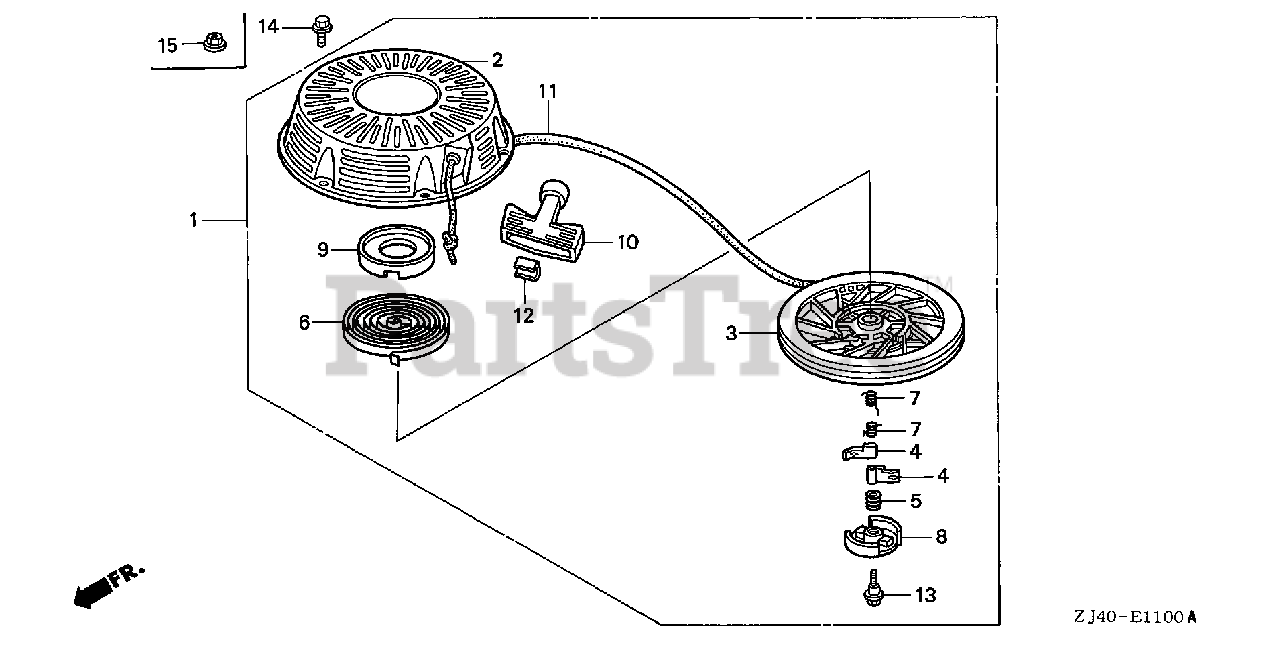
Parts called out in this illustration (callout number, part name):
1	STARTER ASSY., RECOIL *NH1* (BLACK)
1	STARTER ASSY., RECOIL *R280* (POWER RED)
2	CASE, RECOIL STARTER *NH1* (BLACK)
2	CASE, RECOIL STARTER *R280* (POWER RED)
3	PULLEY, RECOIL STARTER
4	RATCHET, STARTER
5	SPRING, FRICTION
6	SPRING, STARTER RETURN
7	SPRING, RATCHET
8	RETAINER, SPRING
10	GRIP, STARTER
11	ROPE, RECOIL STARTER
13	SCREW, CENTER
15	NUT, FLANGE (6MM)
